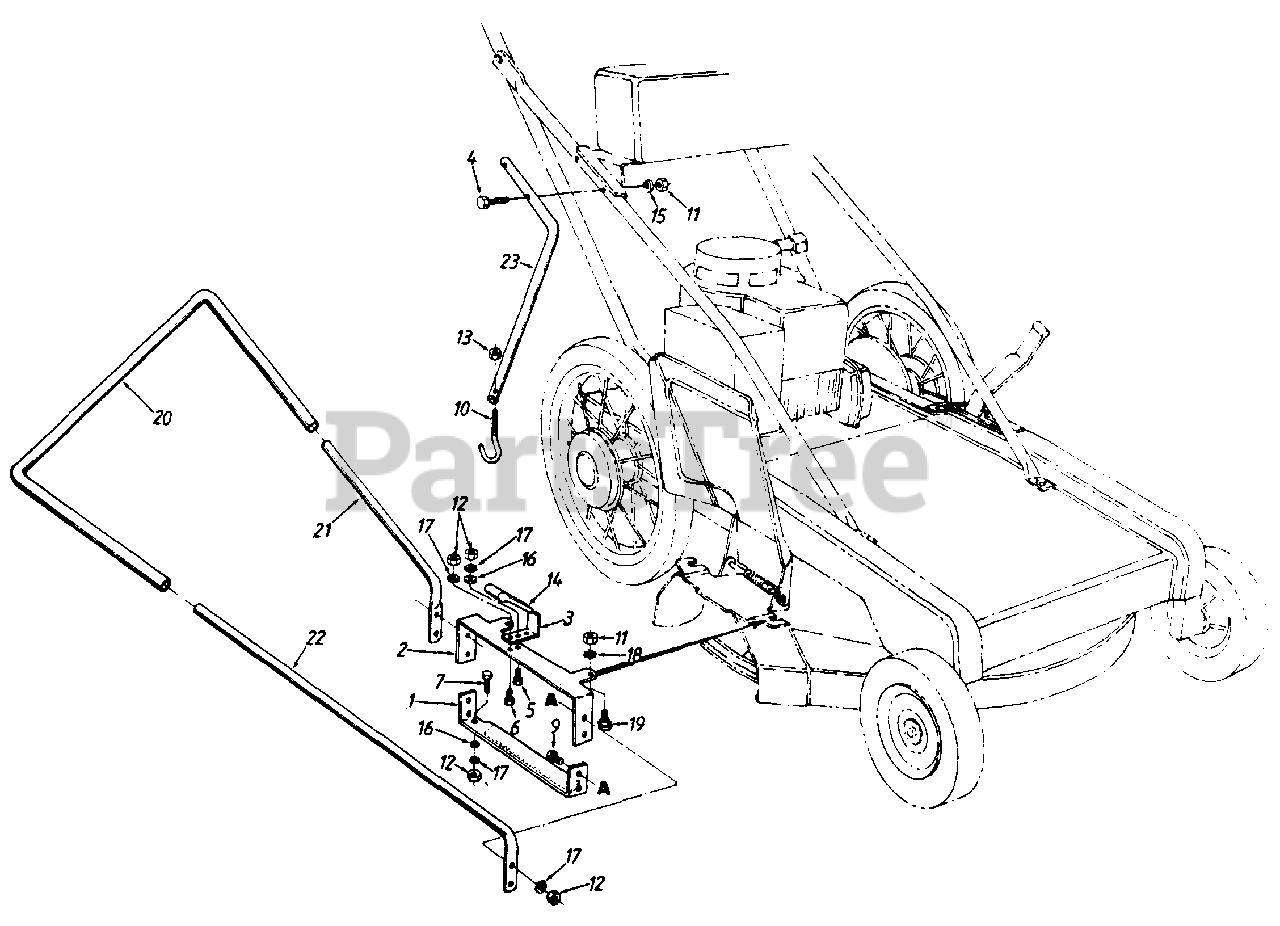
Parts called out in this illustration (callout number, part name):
1	Lower Opening Support
2	Upper Opening Support
5	Hex Bolt 1/4-20 x .85" Lg.
6	Hex Bolt 1/4-20 x .62" Lg.
7	Hex Bolt 1/4-20 x .5" Lg.
11	Hex Nut 5/16-18 Thd.
12	Hex Nut 1/4-20 Thd.
13	Hex Ins. Nut 1/4-20 Thd.
15	L-Wash. 5/16" I.D.
16	R-Wash..281 I.D. x .5 O.D.
17	Ext. L-Wash. 1/4" I.D.
18	Ext. L-Wash. 5/16" I.D.
19	Shoulder Bolt
20	Upper Frame
21	Lower Frame
22	Lower Frame Arm
23	Holding Arm
